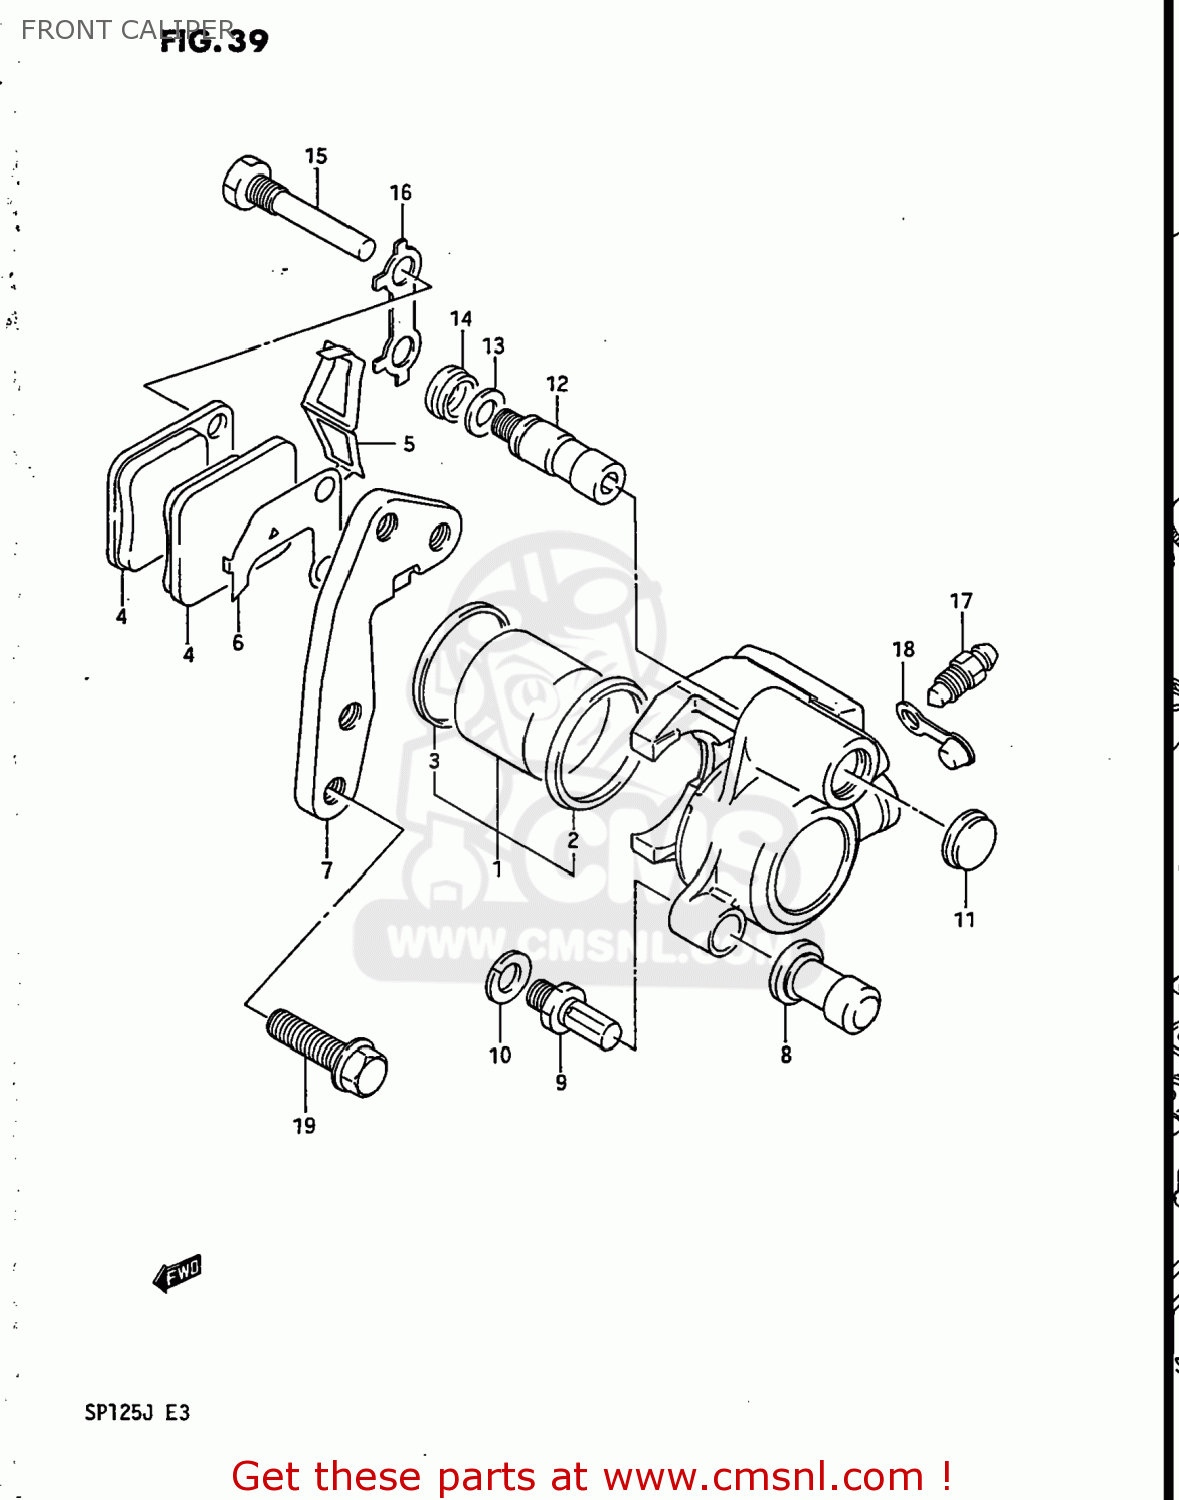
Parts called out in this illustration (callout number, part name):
1	PISTON SET,CALIPERS
2	SEAL,PISTON
3	BOOT,PISTON
4	PAD
5	SPRING,PAD
6	SHIM
7	BRACKET
8	BOOT
9	BOLT,PIN
10	WASHER,WAVE
11	DUST SEAL
12	PIN,SLIDE
13	SPRING,FRICTION
14	BOOT,PIN
15	PIN,HANGER
16	WASHER
17	BLEEDER
18	CAP,BLEEDER
19	BOLT 8X30
